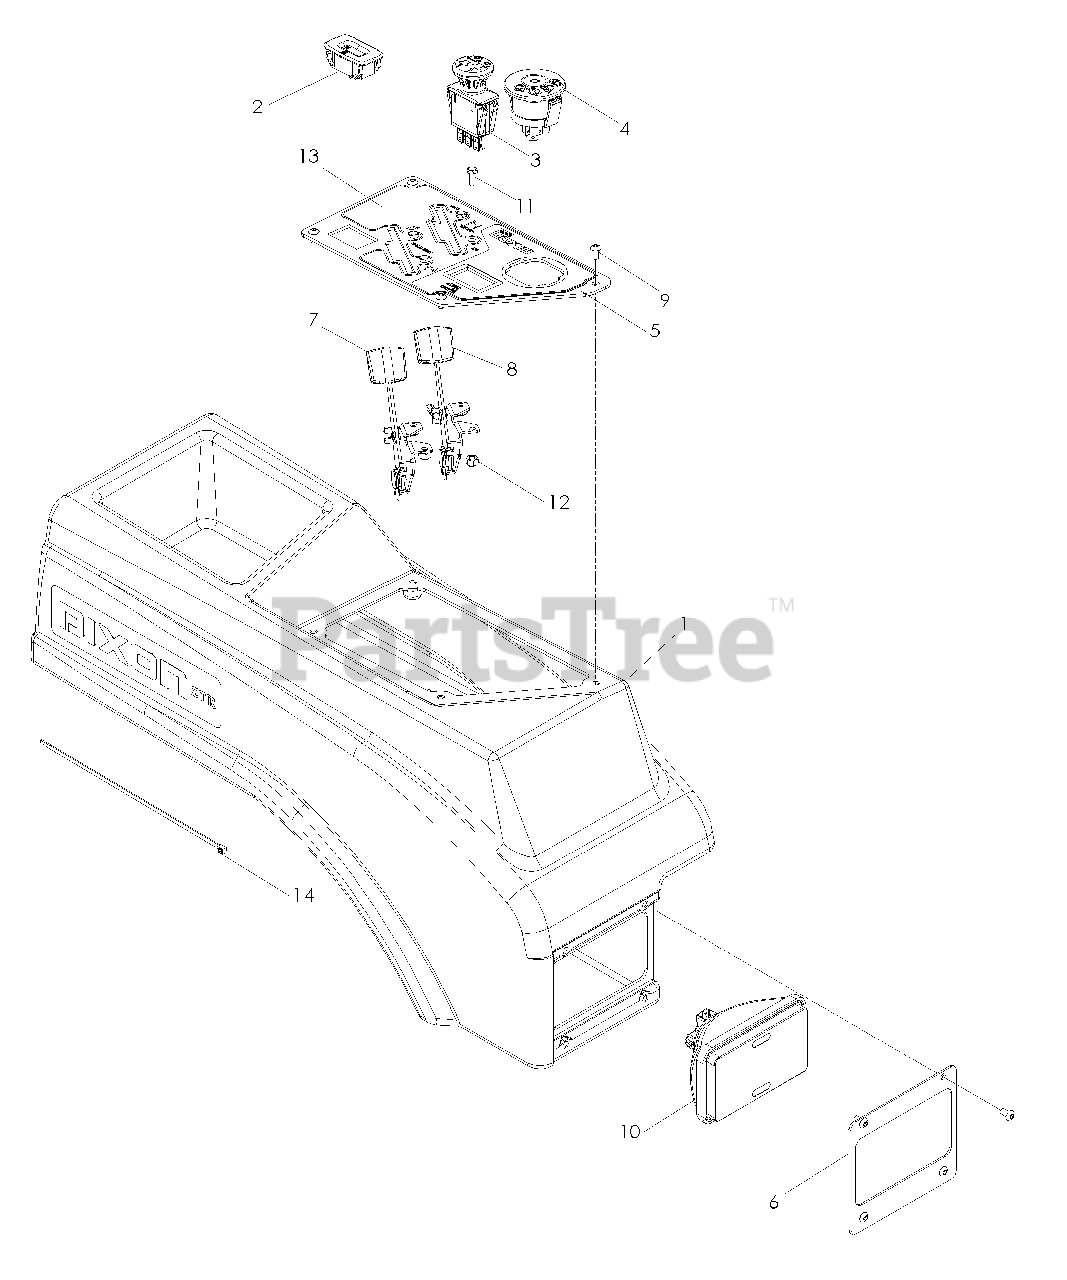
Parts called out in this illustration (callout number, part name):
1	TANK, CONSOLE, RT
2	HOUR METER
3	SWITCH, PTO 10 AMP
4	IGNITION SWITCH
5	CONTROL PANEL
6	PLATE LIGHT
7	CABLE THROTTLE
8	CABLE CHOKE
9	SCR #10-24 X 3/8 SKT HD BLK OX
11	HCS #10-24 X 1/2
12	NUT 10-24 NYLOC
13	DECAL, CONTROL
14	TIE, PLASTIC
